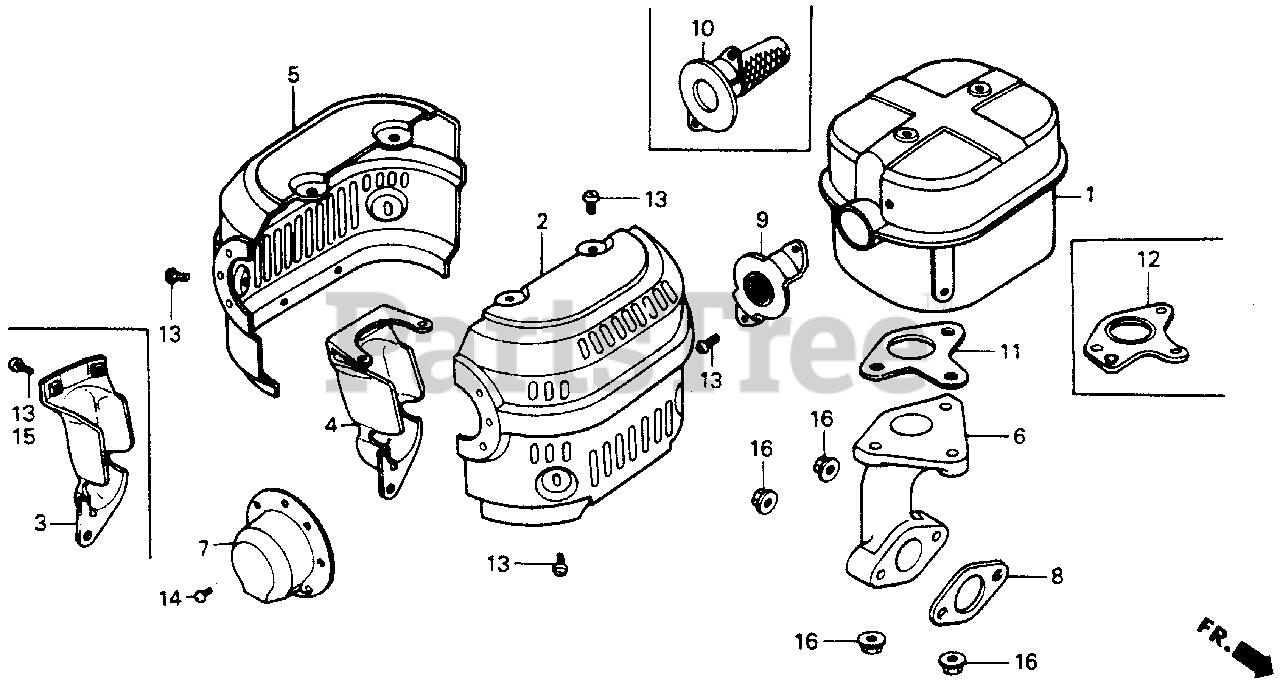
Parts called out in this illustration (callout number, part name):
1	MUFFLER
2	PROTECTOR, R. MUFFLER (ALUMINIZED)
2	PROTECTOR, R. MUFFLER
3	PROTECTOR, EX. PIPE
4	PROTECTOR, EX. PIPE
5	PROTECTOR, L. MUFFLER (ALUMINIZED)
6	PIPE, EX.
7	CAP, MUFFLER
8	GASKET, EX. PIPE
8	GASKET, EX. PIPE (WACKER)
9	FLANGE, BAFFLE
10	ARRESTER, SPARK
11	GASKET, MUFFLER
12	GASKET, MUFFLER
13	SCREW, TAPPING (5X8)
14	SCREW, TAPPING (4X6)
15	SCREW, PAN (5X8)
16	NUT, FLANGE (8MM)
